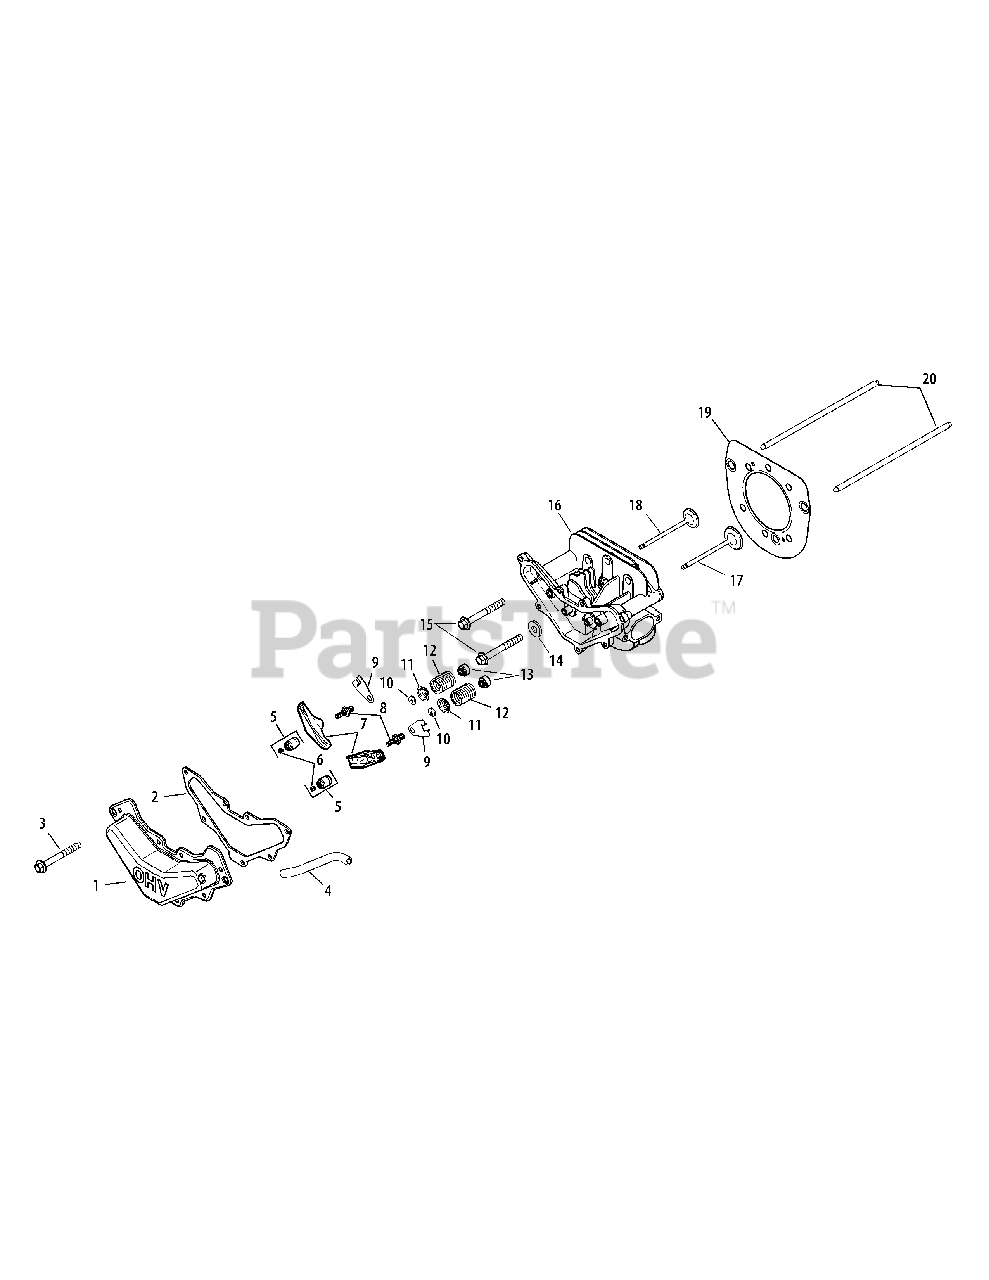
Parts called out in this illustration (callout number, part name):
1	Valve Cover Assembly
2	Valve Cover Gasket
3	Flg. Screw, M6 X 1.0 X 20
4	Breather Hose
5	Rocker Pivot Assembly (Incl. 6)
9	Push Rod Guide Plate
10	Retainer Lock
11	Valve Spring Cap
13	Valve Stem Seal
14	Flat Washer, 13/32
15	Flange Screw, M10 X 1.5 X 80
16	Kit, Cylinder Head
17	Exhaust Valve
19	Cylinder Head Gasket Kit
